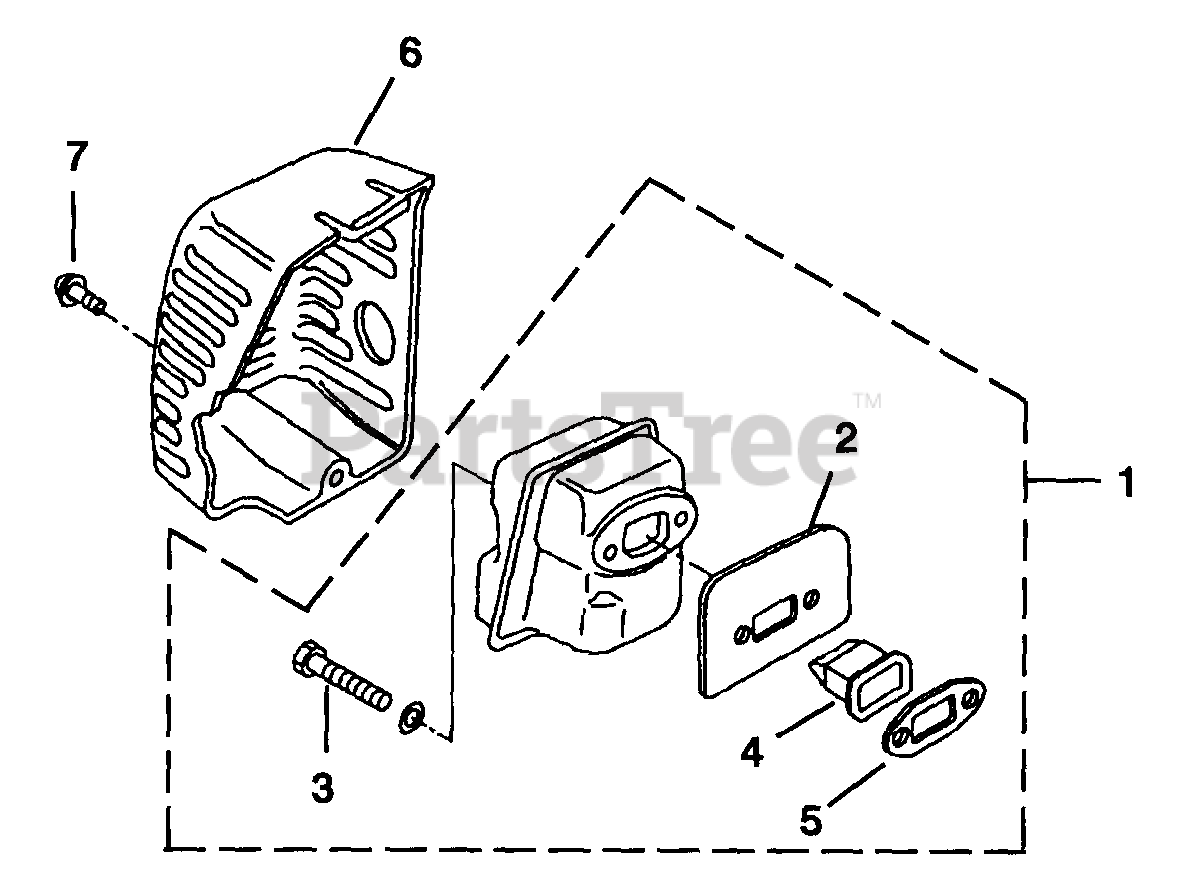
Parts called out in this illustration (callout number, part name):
1	MUFFLER KIT
2	GASKET-Muffler
3	SCREW-Socket Hd (M5 x 50)
4	SPARK ARRESTOR SCREEN
5	GASKET-Muffler
6	MUFFLER COVER
7	SCREW ASSEMBLY (M5 x 16)
